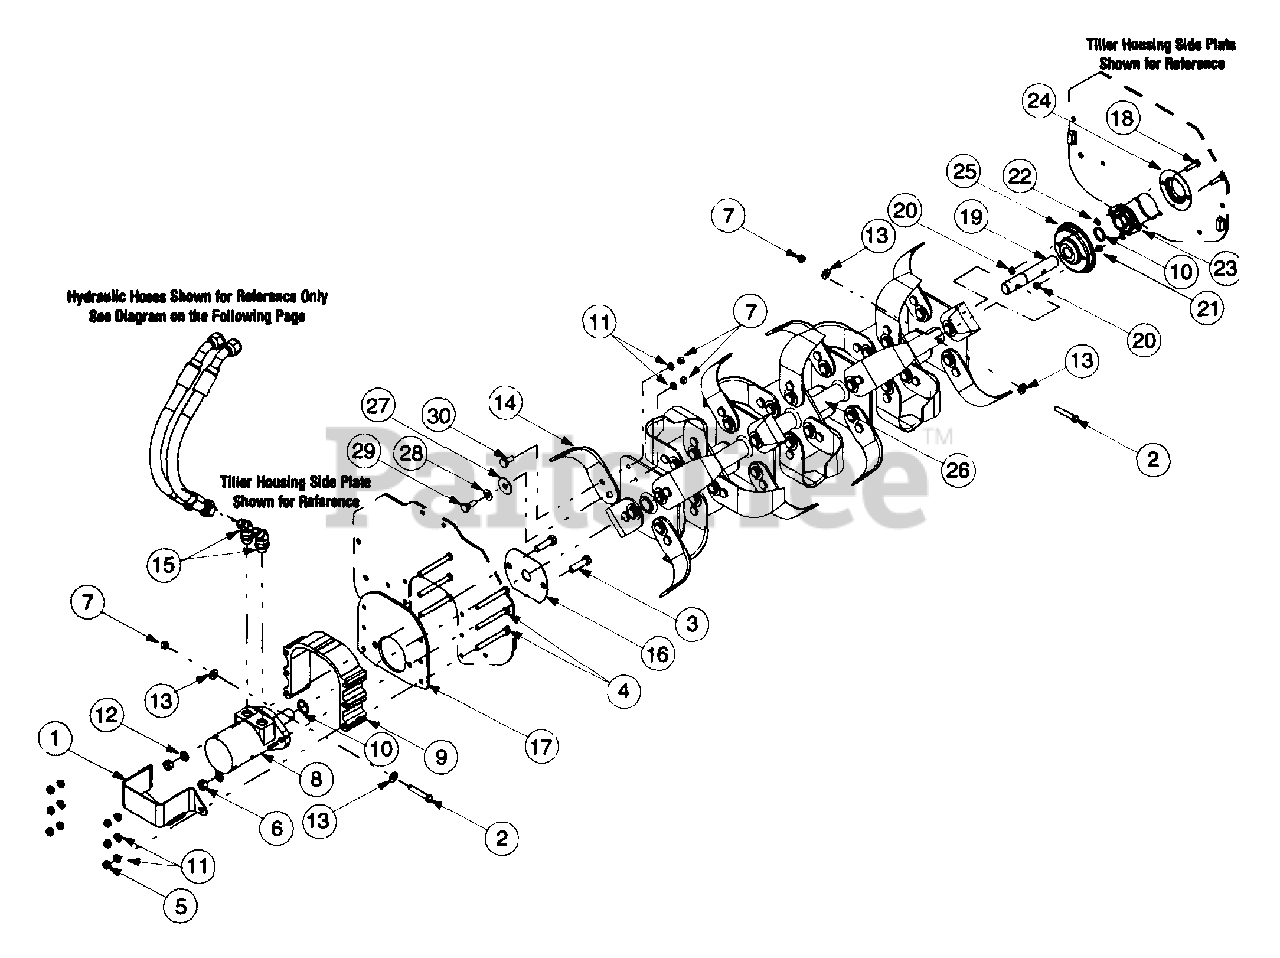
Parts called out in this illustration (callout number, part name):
1	Hydraulic Motor Guard
2	Hex Cap Screw, 3/8-24 x 2.25
3	Hex Cap Screw, 1/2-13 x 1.75
4	Hex Cap Screw, 3/8-16 x 3.5
5	Hex Lock Nut, 3/8-16
6	Hex Lock Nut, 1/2-13
7	Hex Lock Nut, 3/8-24
8	Eaton Hyd. Motor (101-2716-009)
9	Hydraulic Motor Mounting Spacer
10	O Ring Seal
11	Lock Washer, 3/8
12	Lock Washer, 1/2
13	Flat Washer, .406 x .875 x .105
14	Articulating Tine
15	45° Hydraulic Adapter 7/8
16	Hydraulic Motor Cover
17	Hydraulic Motor Mounting Plate
18	Hex Cap Screw, 5/16-18 x 1.25
19	Tine Shaft
20	Hex Lock Nut, 5/16-18
21	Hex Nut, 5/16-18
22	Lock Washer, 5/16
23	Flange Bearing, 1.0
24	Dust Cap Cover
25	Bearing Cover
26	Tine Adapter Assembly
27	Flat Washer, .51 x 1.5 x .07
28	Belleville Washer
29	Shoulder Screw, .49 x .34, 3/8-24
30	Shoulder Screw .49 x .21 3/8-24
